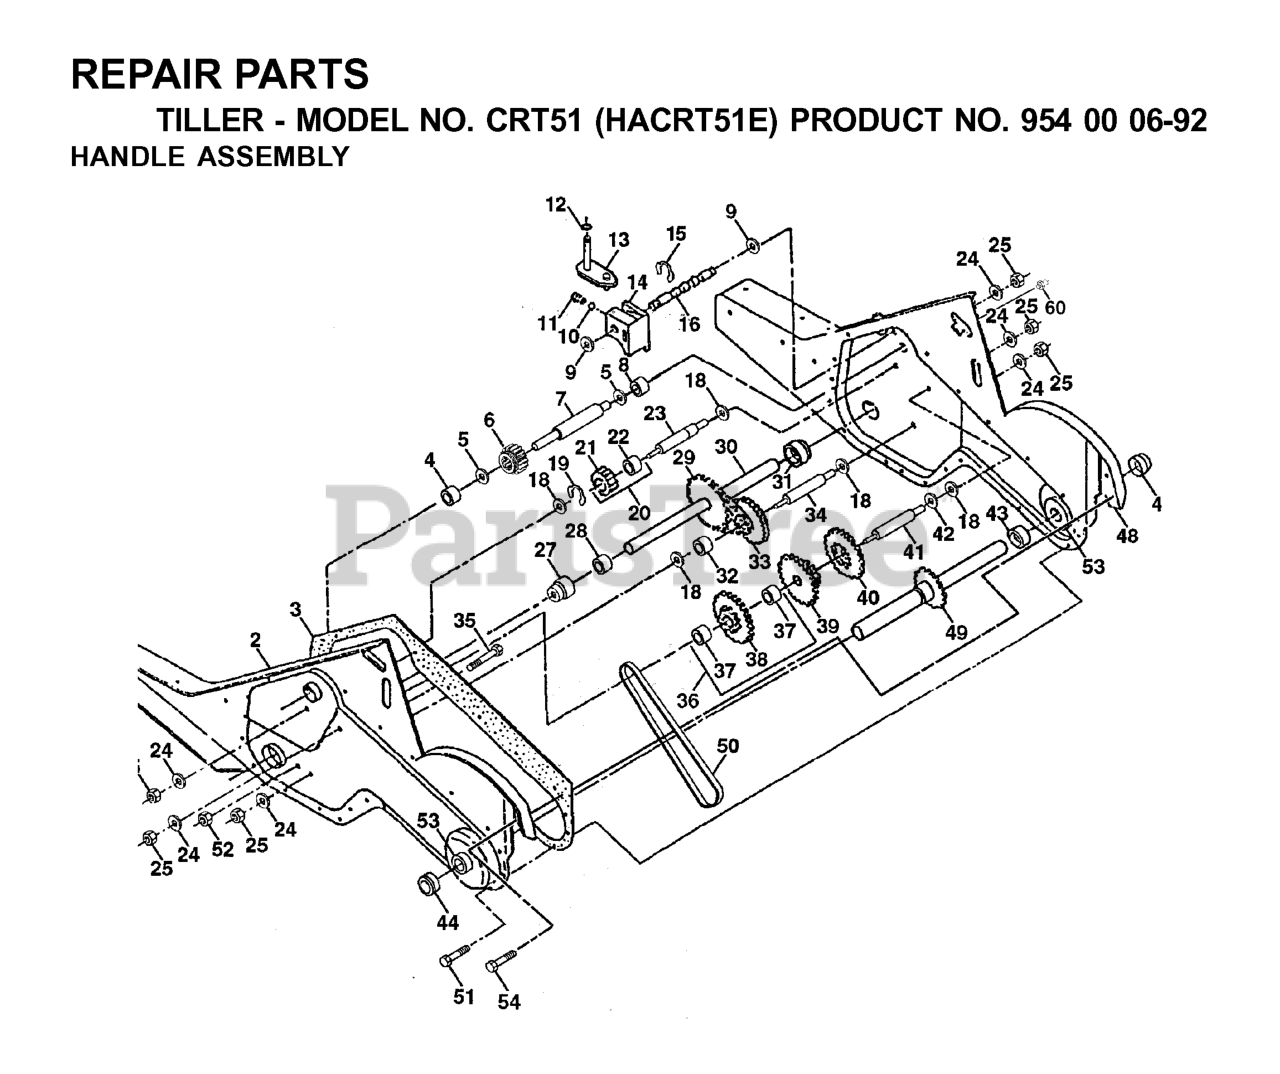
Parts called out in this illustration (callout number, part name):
1	CONT,THROTTLE
2	KIT.GRIP.HANDLE.5.00.BLK.VINYL
4	CONTROL BAR ASSY
8	SCREW.PNHD.10-24
10	GRIP T
11	RETAINER M
12	SHOULDER BOLT ST
13	SHIFT HANDLE CRT
14	GROMMET.RUBBER.CRT.TILLER
15	SHIFT ROD CRT
16	BOLT D
17	LOCK.HANDLE.CRT
19	WASHER CRT
20	LEVER.LOCK.CRT
21	HANDLE
23	TAPPING SCREW
24	CONDUIT.CLIP.PLATED
26	CABLE.CLUTCH
27	NUT T
29	NUT **
30	TIE CABLE CRT
31	BOLT.PIVOT
37	GRIP BAR CRT(1)
41	CLAMP.BAR.CRT.BLACK
